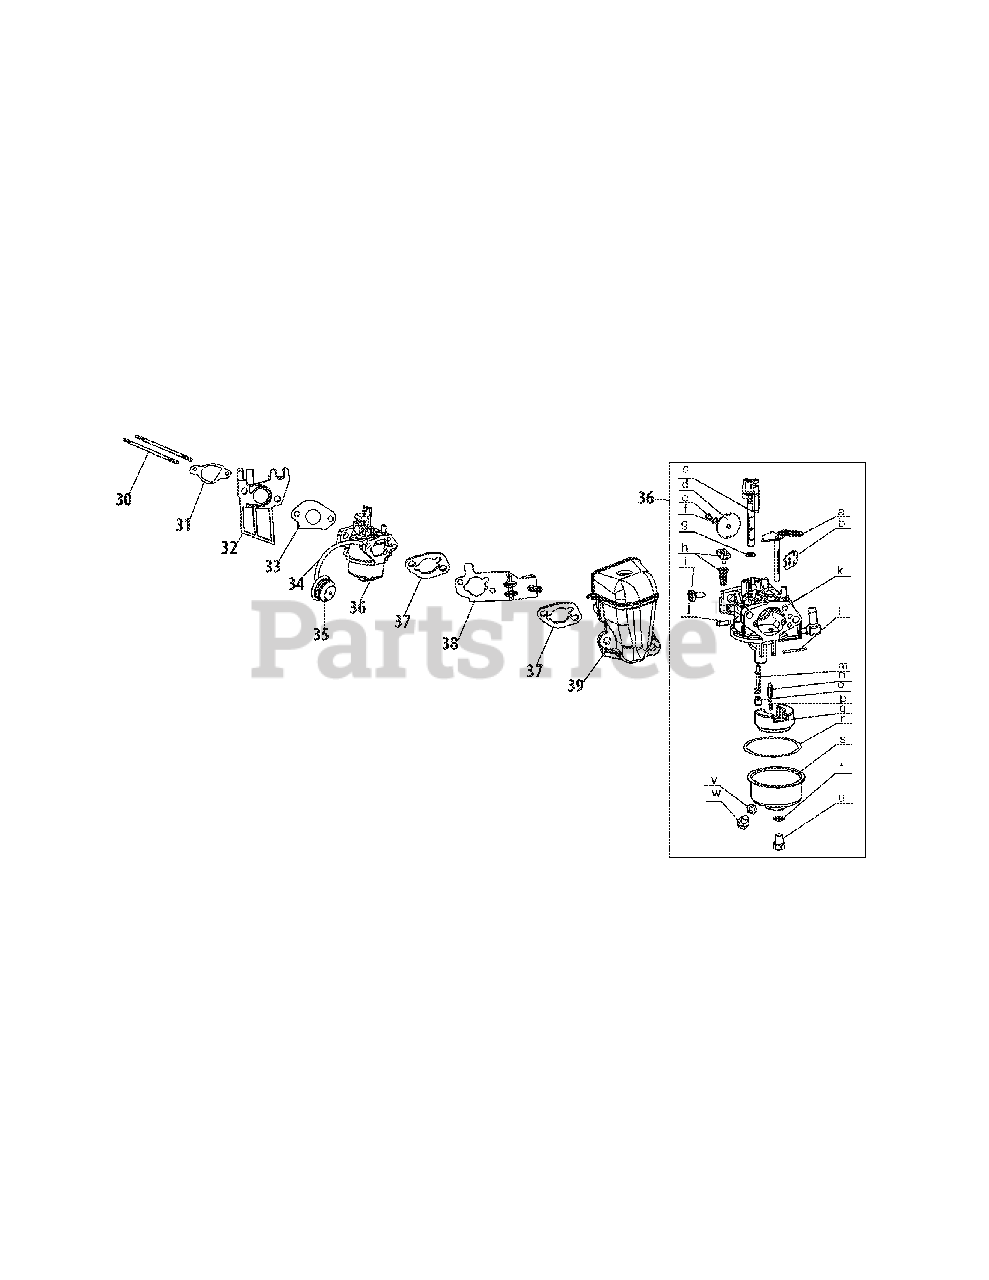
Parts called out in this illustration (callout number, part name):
30	STUD M6×92
31	GASKET, CARBURETOR INSULATOR
32	INSULATOR , CARBURETOR
33	CARBURETOR GASKET
34	FUEL HOSE 3.2×6.5×150
36	CARBURETOR
37	AIR FILTER GASKET
38	CHOKE CONTROLER ASSY
39	HEATER BOX
